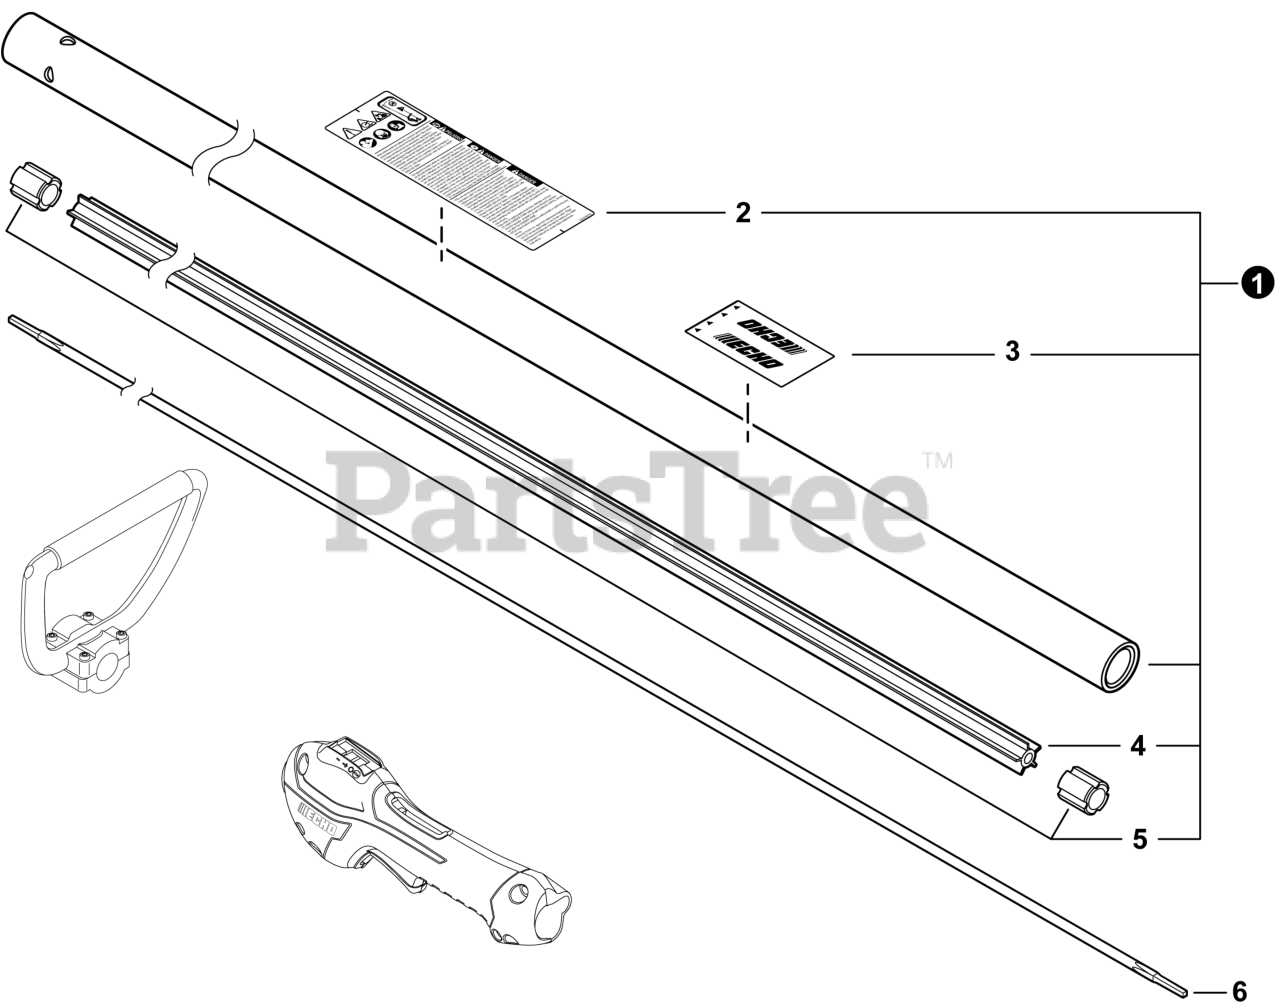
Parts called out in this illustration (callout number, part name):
1	MAIN PIPE ASSY
2	LABEL - CAUTION
3	LABEL - HANDLE LOCATION
4	LINER, FLEXIBLE 21.6x1420
6	DRIVESHAFT - FLEXIBLE
